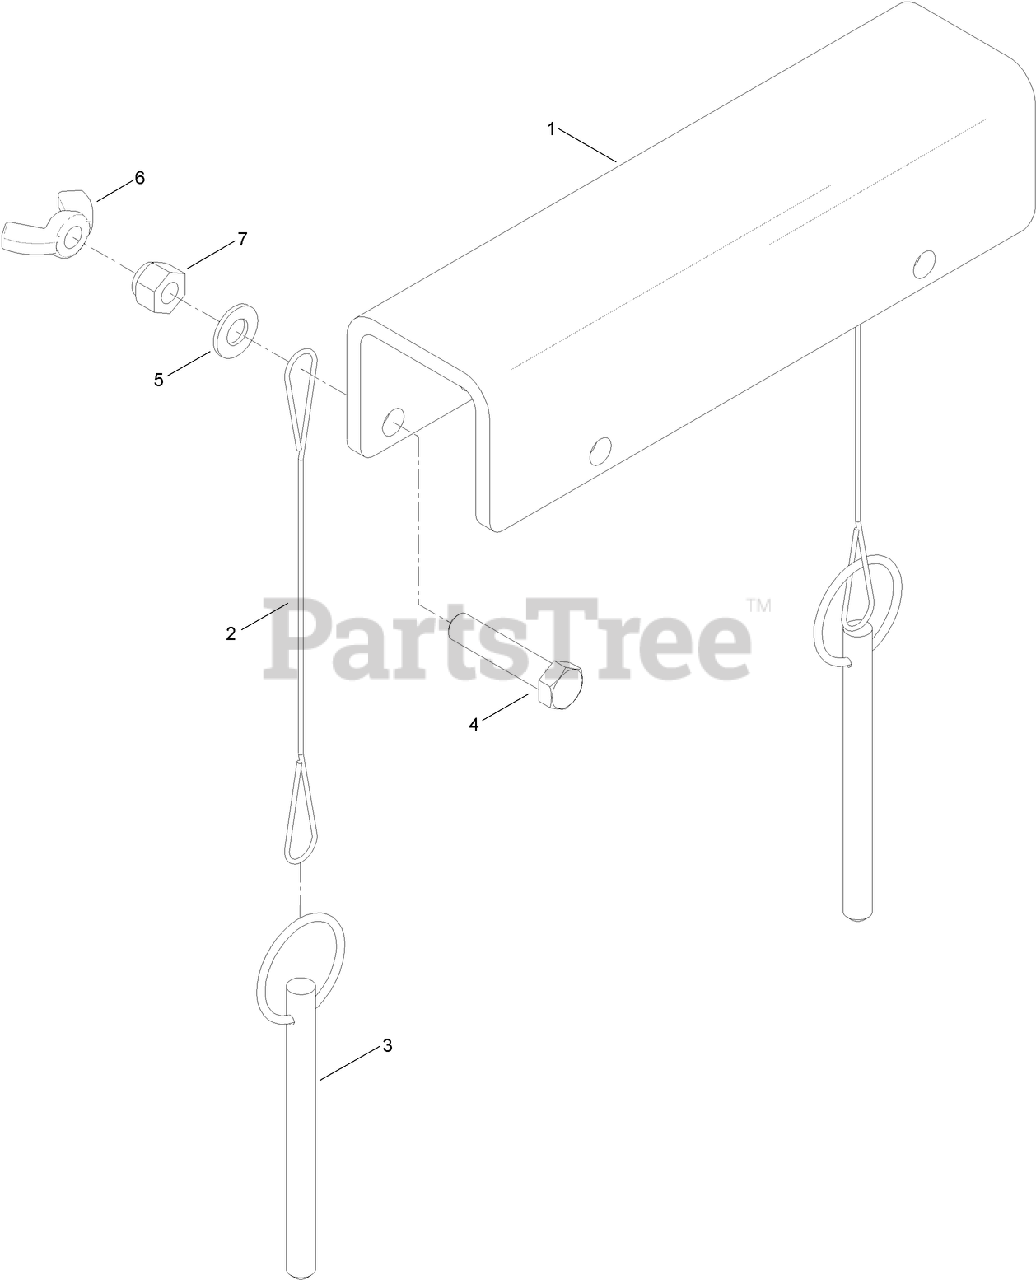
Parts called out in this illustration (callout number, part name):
1	PLATE-LOCKOUT, TILT CYLINDER
2	LANYARD-TETHER, PIN
3	PIN-RETAINING
4	SCREW-HH
5	WASHER-FLAT
6	NUT-WING
7	NUT-LOCK, NI
